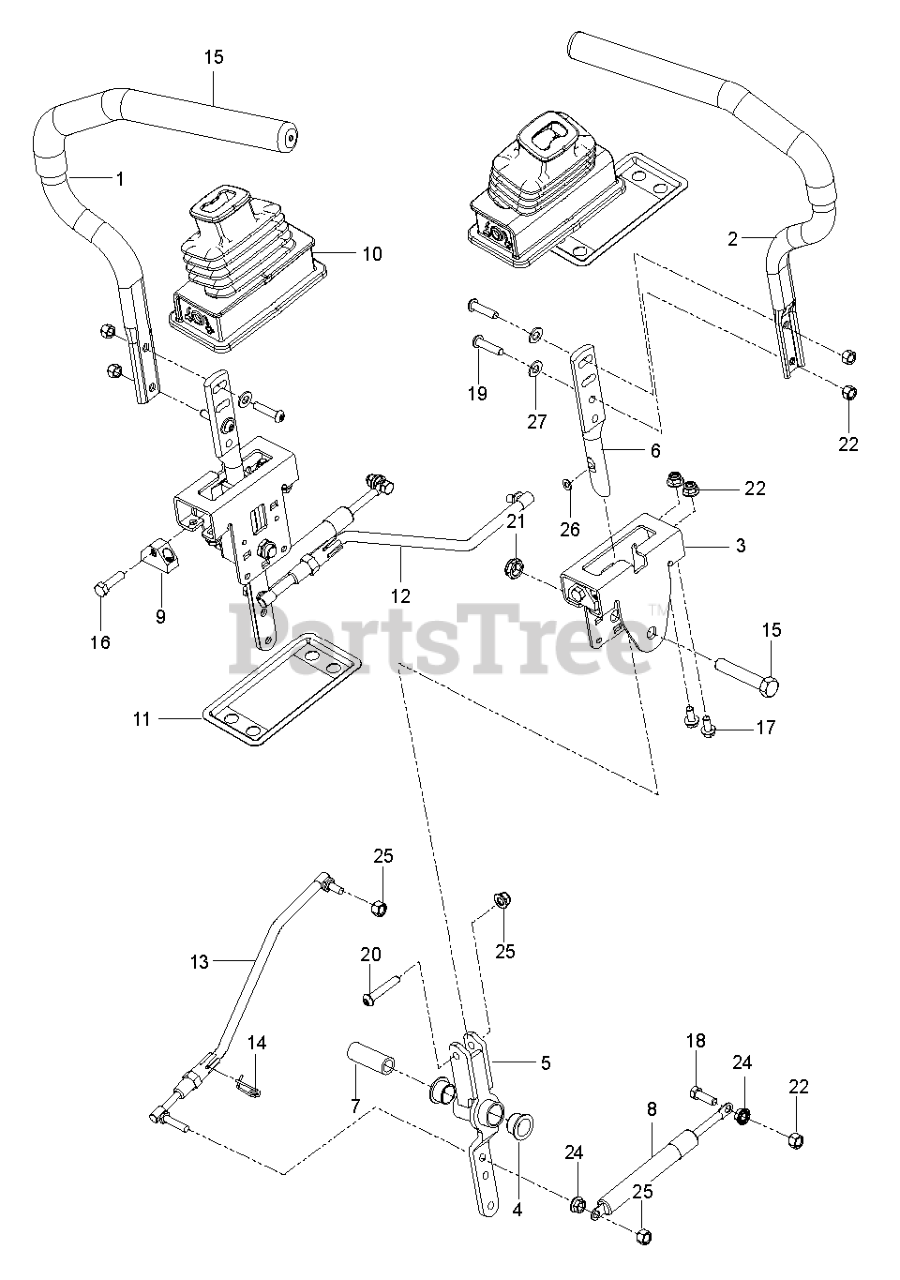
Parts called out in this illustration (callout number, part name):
1	TUBE.LEVER.CNTL.ASM.ZTR.RT.SVC
2	TUBE.LEVER.CNTL.ASM.ZTR.LT.SVC
3	BRACKET.CONTROLS.ZTR.X431
4	BEARING, FLANGE
5	LEVER CONTROL PIVOT
6	CONTROL.LEVER.HANDLE
7	SPACER.PIVOT.CONTROL
9	BLOCK TRACKING CONTROL ZTR
10	BOOT.STEERING.LEVER
11	CONTROL.BOOT.FLANGE.X431
12	ROD.ASM.RH.ADJUSTABLE
13	ROD.ASM.LH.ADJUSTABLE
14	RETAINER.CLIP.SPRING.S
15	SWITCH.INTLK.RZ.RFRSH.BUTTON
16	HCS 1/2-13 X 2-3/4 GD 5 ZD
17	SCREW.SHAKEPROOF.1.25.BLACK
18	HHFS 5/16-18 X 3/4
19	HCS 5/16C X 1
20	SCREW.CAP.SOCKET.6PT.5/16-18
21	BUTTONHEAD.5/16-18X1.125.BLACK
22	SCREW.BUTTONHD.10-24X1/2.(2 2)
23	NUT 1/2-13 HEX JM NYL
24	5/16-18 NYLOC FLANGE NUT
25	NYLOCK.NUT.5/16-18 BLACK
26	NUT 5/16C WHIZ
27	NUT.71038.31-18.HEX.NYLOCK
28	WASHER
